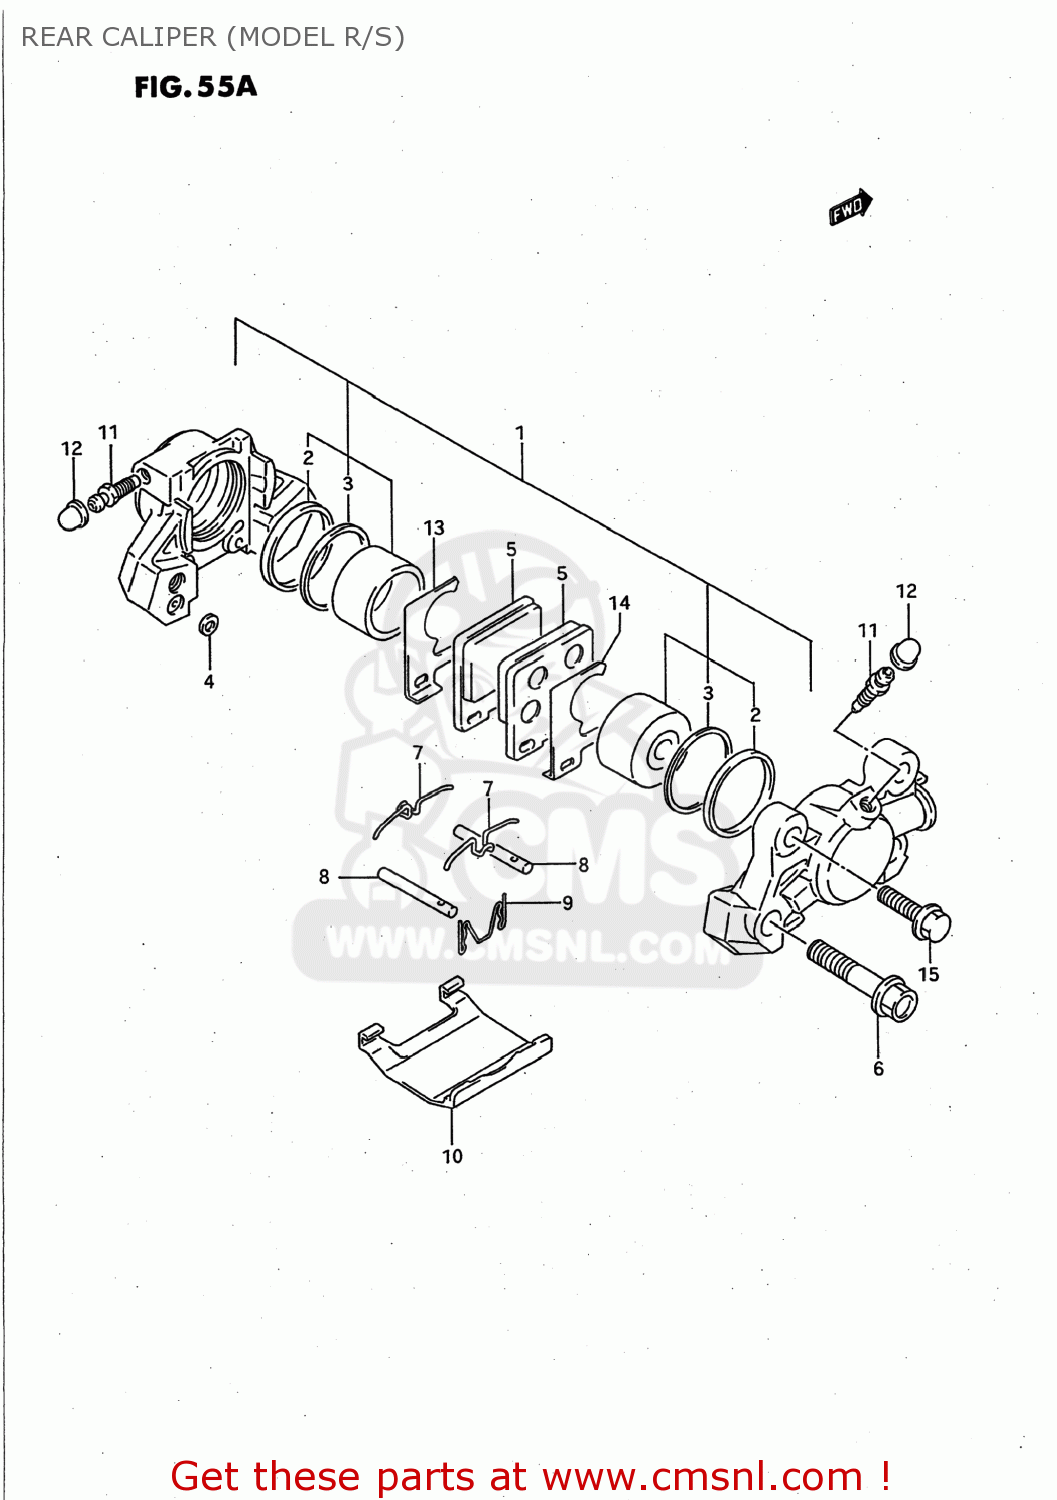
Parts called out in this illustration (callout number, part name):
1	PISTON SET
2	SEAL,PISTON
3	SEAL,WIPER
4	SEAL,JOINT
5	PAD,BRAKE
6	BOLT
7	SPRING
8	PIN,PAD
9	CLIP,PAD PIN
10	COVER
11	BLEEDER
12	CAP,BLEEDER PLUG
13	SHIM,INNER
14	SHIM,OUTER
15	BOLT
